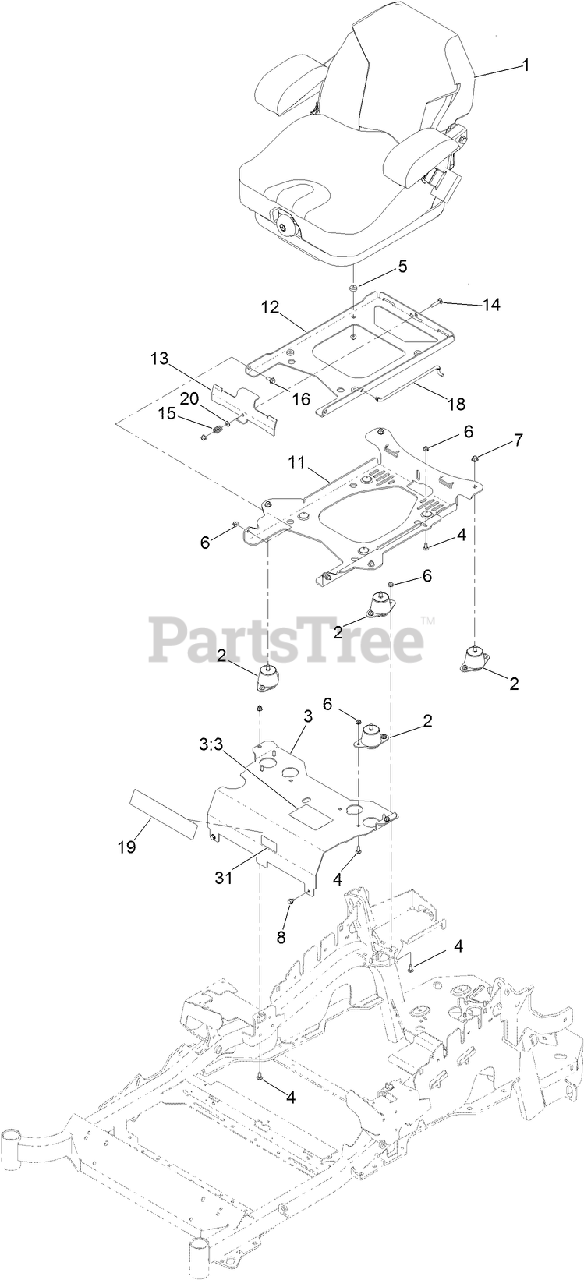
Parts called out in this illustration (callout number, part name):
1	SUSPENSION SEAT ASM
2	ISOLATOR-SEAT
3	SEAT MOUNT ASM
3:3	DECAL-SERVICE AID
4	SCREW-CARR
5	SPACER-PIN, MOUNTING
6	NUT-HF, NI
7	NUT-HF, NI
8	SCREW
11	PLATE-TILT, SEAT SUPPORT
12	PLATE-FRAME, SEAT
13	PLATE-LATCH, SEAT
14	BOLT-CARR
15	SPRING-COMPRESSION
16	SCREW-SHOULDER
18	ROD-PROP
19	DECAL
20	WASHER-PLAIN
31	DECAL-EFI
